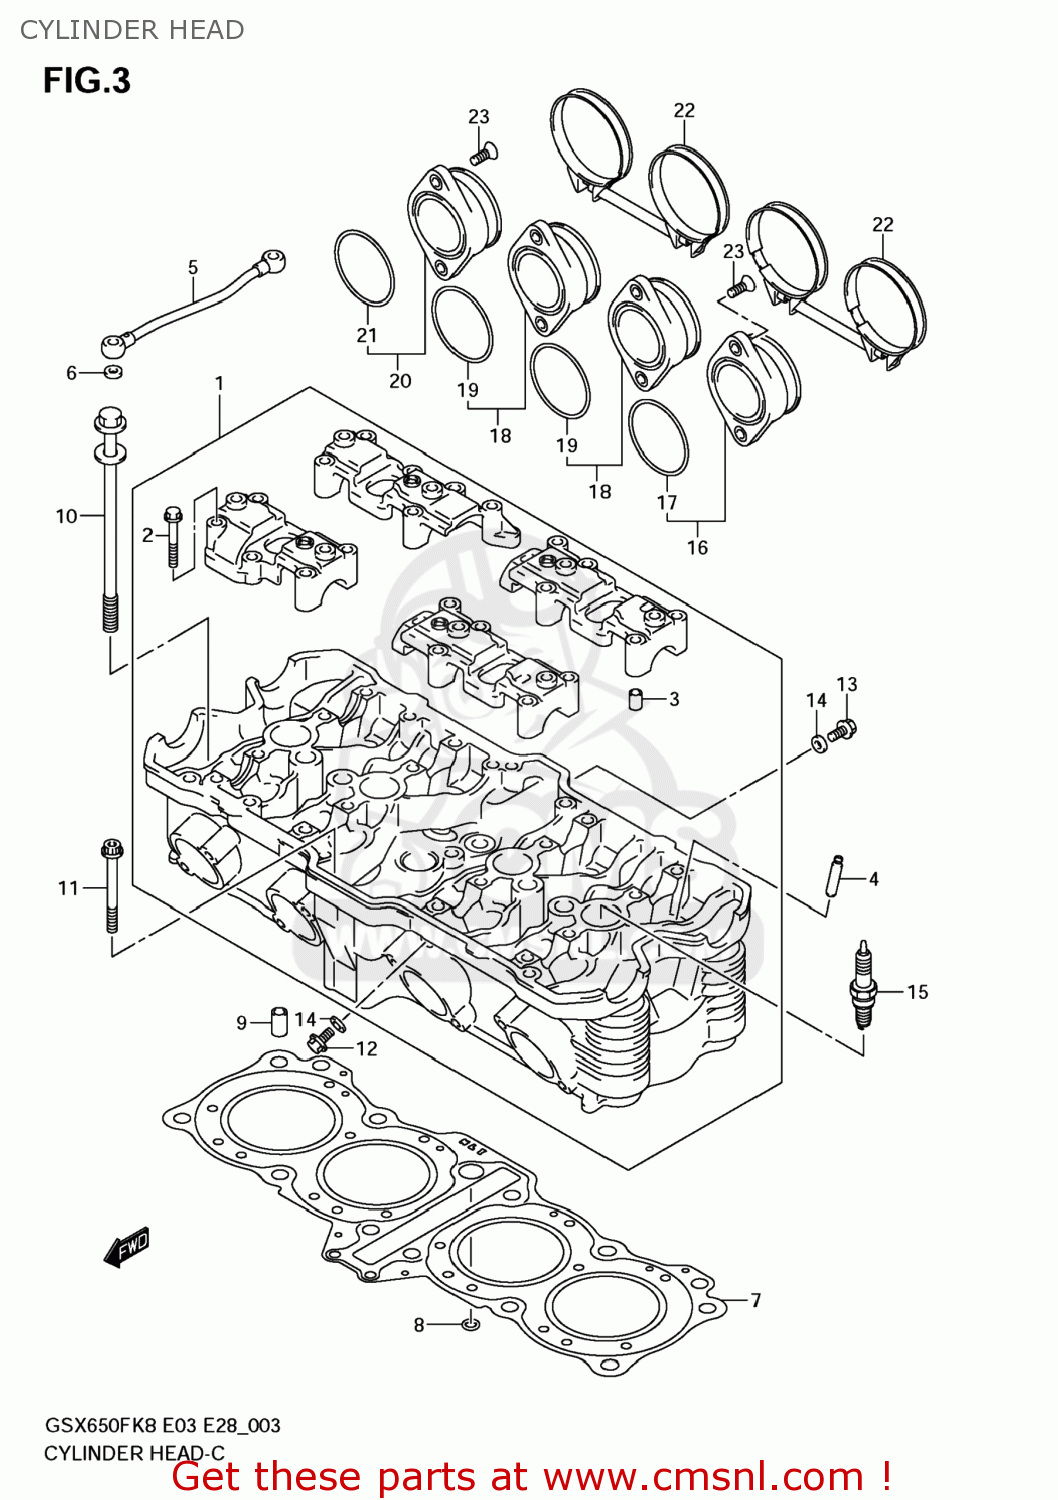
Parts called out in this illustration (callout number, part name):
1	HEAD ASSY,CYLINDER
2	BOLT(6X45)
3	PIN(6.2X8X11)
4	GUIDE,VALVE
5	PIPE,CYLINDER HEAD OIL
6	WASHER
7	GASKET,CYLINDER HEAD (NAS)
8	O RING,HEAD GASKET
9	PIN
10	BOLT,CYLINDER HEAD(L:175)
11	BOLT
12	BOLT
13	BOLT
14	GASKET(5.8X13X1.2) (NAS)
15	PLUG,SPARK(CR8E)
16	PIPE ASSY,INTAKE NO.1
17	O RING(D:2.4,ID:41.7)
18	PIPE ASSY,INTAKE NO.2
19	O RING(D:2.4,ID:41.7)
20	PIPE ASSY,INTAKE NO.4
21	O RING(D:2.4,ID:41.7)
22	CLAMP,INTAKE PIPE
23	SCREW
